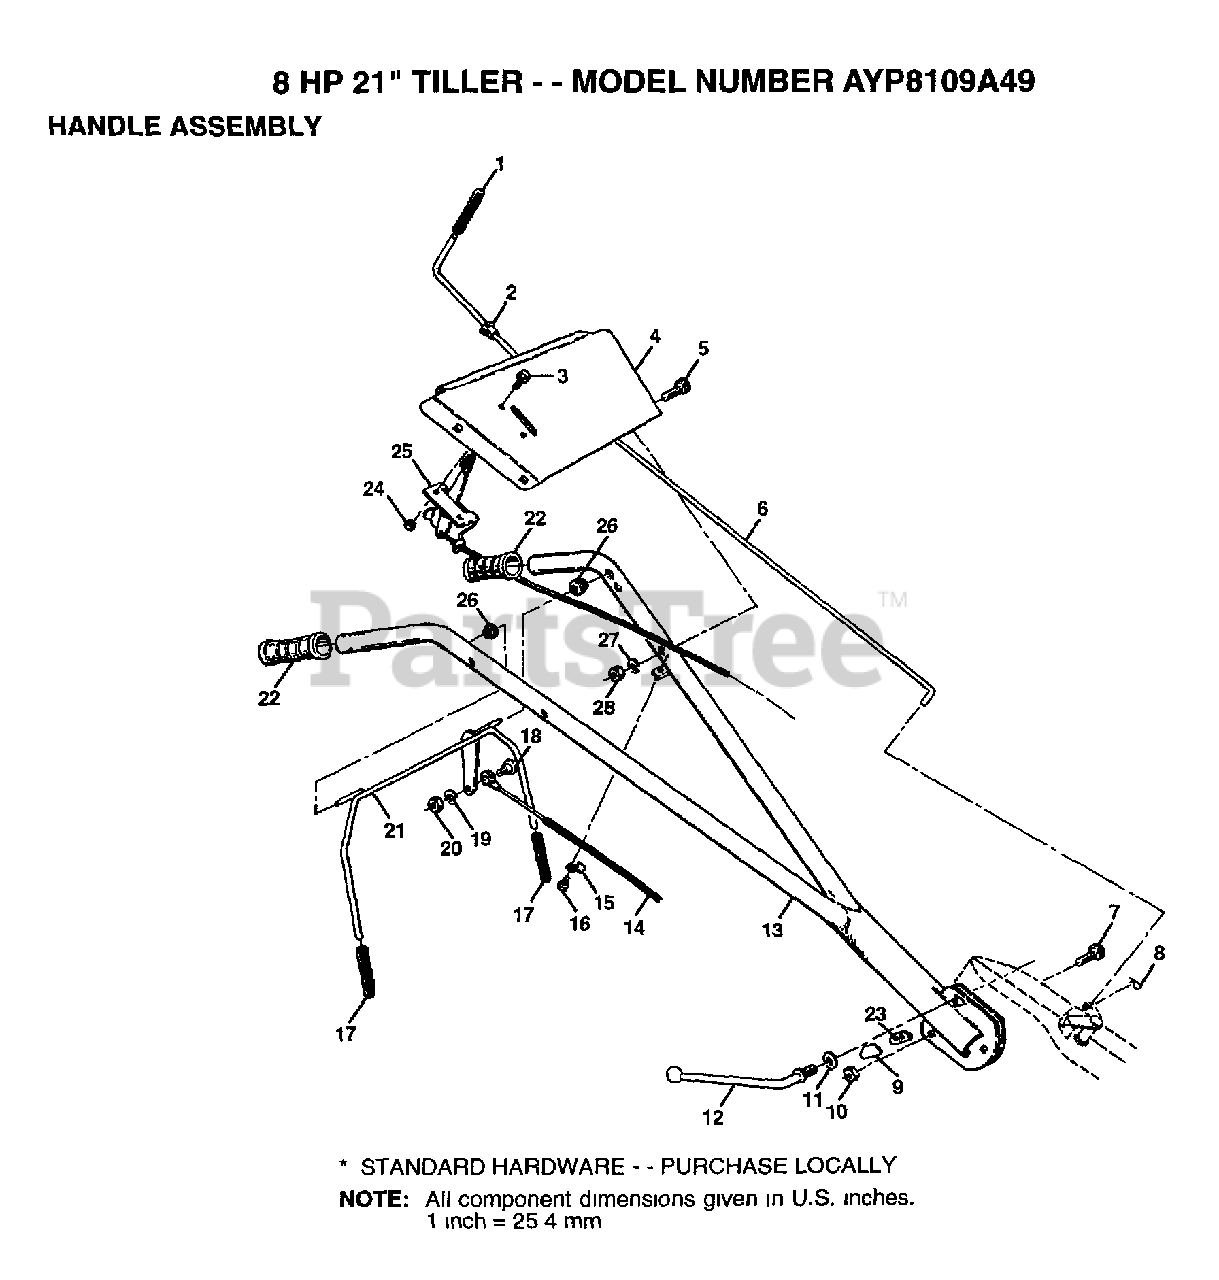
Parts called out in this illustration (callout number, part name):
1	GRIP TI
2	BUSHING
3	SCREW
4	HANDLE BRACKET
5	BOLT CARRIAGE CRT
6	ROD SHIFT CRT
8	RETAINER M
9	LOCK CRT
10	LOCKNUT
11	WASHER CRT
12	LEVER LOCK CRT
14	CABLE-CLUTCH CRT
15	CONDIUT CLIP T
17	GRIP BAR CRT
18	SHOULDER BOLT ST
19	LOCKWASHER
21	HANDLE BAR CRT
22	GRIP HDLE NUBBED
23	LOCK.HANDLE
25	CONTROL.THROTTLE
27	LOCKWASHER
28	NUT
